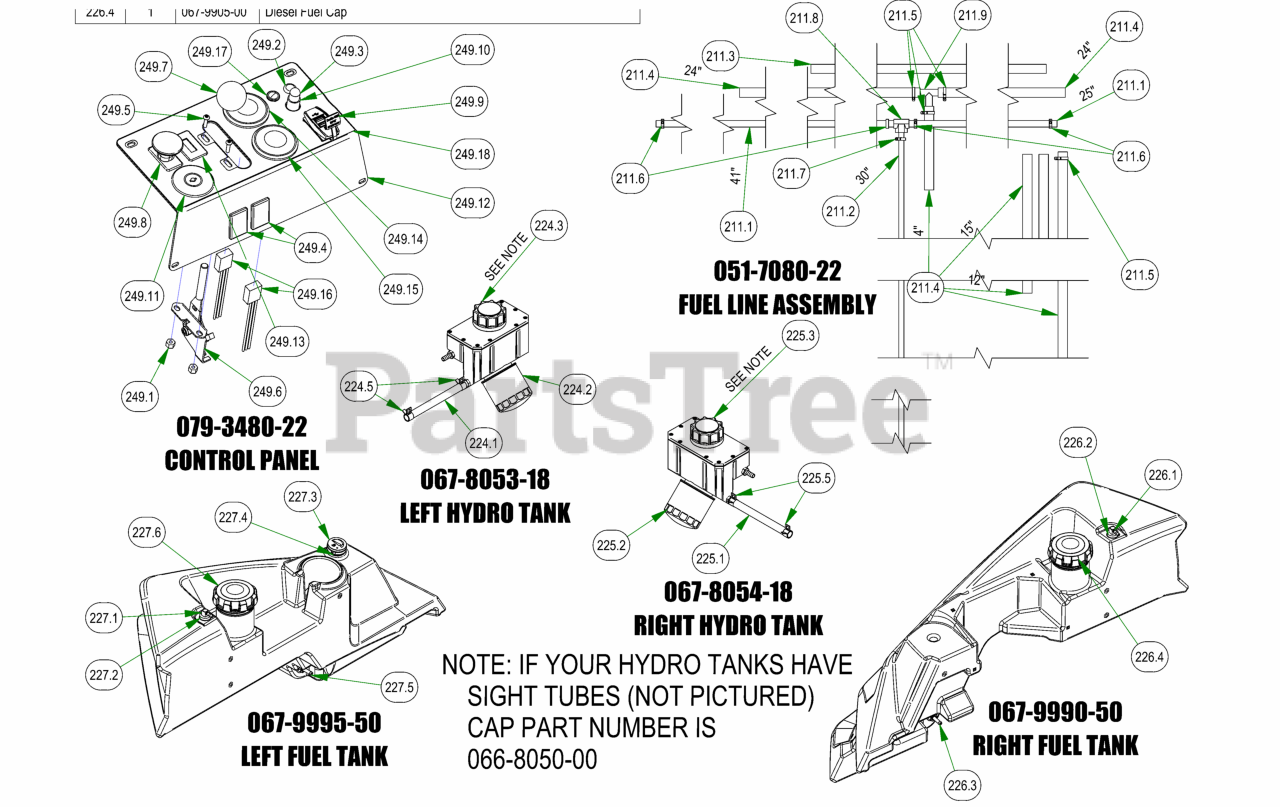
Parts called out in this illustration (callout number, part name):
211	2022 Renegade Diesel Fuel Line Assembly
211.1	1/4" Fuel Line Hose
211.2	3/16 Fuel Line
211.3	5/16 Clear Hose
211.4	5/16" fuel line hose
211.5	5/16 Fuel Line Clamp
211.6	1/4 Fuel Hose Clamp
211.7	3/16 Vinyl Clamp
211.8	Brass fuel line T
211.9	5/16 x 5/16 x 1/4 Fuel Line T
224	LH Rogue Hydro Tank Assy
224.1	1/2 Clear Braded Hose Priced/FootSE
224.2	N Hydraulic FilterOTE
224.3	Hydraulic Tank Cap W/Dipstick
224.4	2019 Left Outlaw Gen2 Hydro Tank Suspension Only
224.5	1/2 Hose Clamp
225	RH Rogue Hydro Tank Assy
225.1	1/2 Clear Braded Hose Priced/Foot
225.2	Hydraulic Filter
225.3	Hydraulic Tank Cap W/Dipstick
225.4	2019 Right Outlaw Gen2 Hydro Tank Suspension Only
225.5	1/2 Hose Clamp 41
226	2019 Right Renagade Fuel Tank (diesel)
226.1	90 Degree Elbow Fitting
226.2	Nitrile Bushing
226.3	Fuel Pick-up
226.4	Diesel Fuel Cap30"
227	2019 Left Renegade Fuel Tank (Diesel)
227.1	90 Degree Elbow Fitting
227.2	Nitrile Bushing
227.3	Fuel Gauge
227.4	Fuel Gauge Grommet
227.5	Fuel Pick-up
227.6	Diesel Fuel Cap
249	Renegade Control Panel Assembly
249.1	10-24 Nylon Insert Locknut
249.2	5/8 Round Insert
249.3	Start Switch Boot - Diesel
249.4	Light Plug
249.5	10-24 X 5/8 BS Button Head Bolt
249.6	Universal Throttle Head - 2012
249.7	Throttle Knob
249.8	PTO Switch
249.10	Momentary Start Switch
249.11	Ignition Switch
249.12	2019 Diesel Control Panel
249.13	Tachometer
249.14	2" Oil Pressure Gauge
249.15	2" Water Temperature Gauge
249.16	Diesel Gauge Adapter
249.18	2022 Renegade (Diesel) Control Panel Decal
